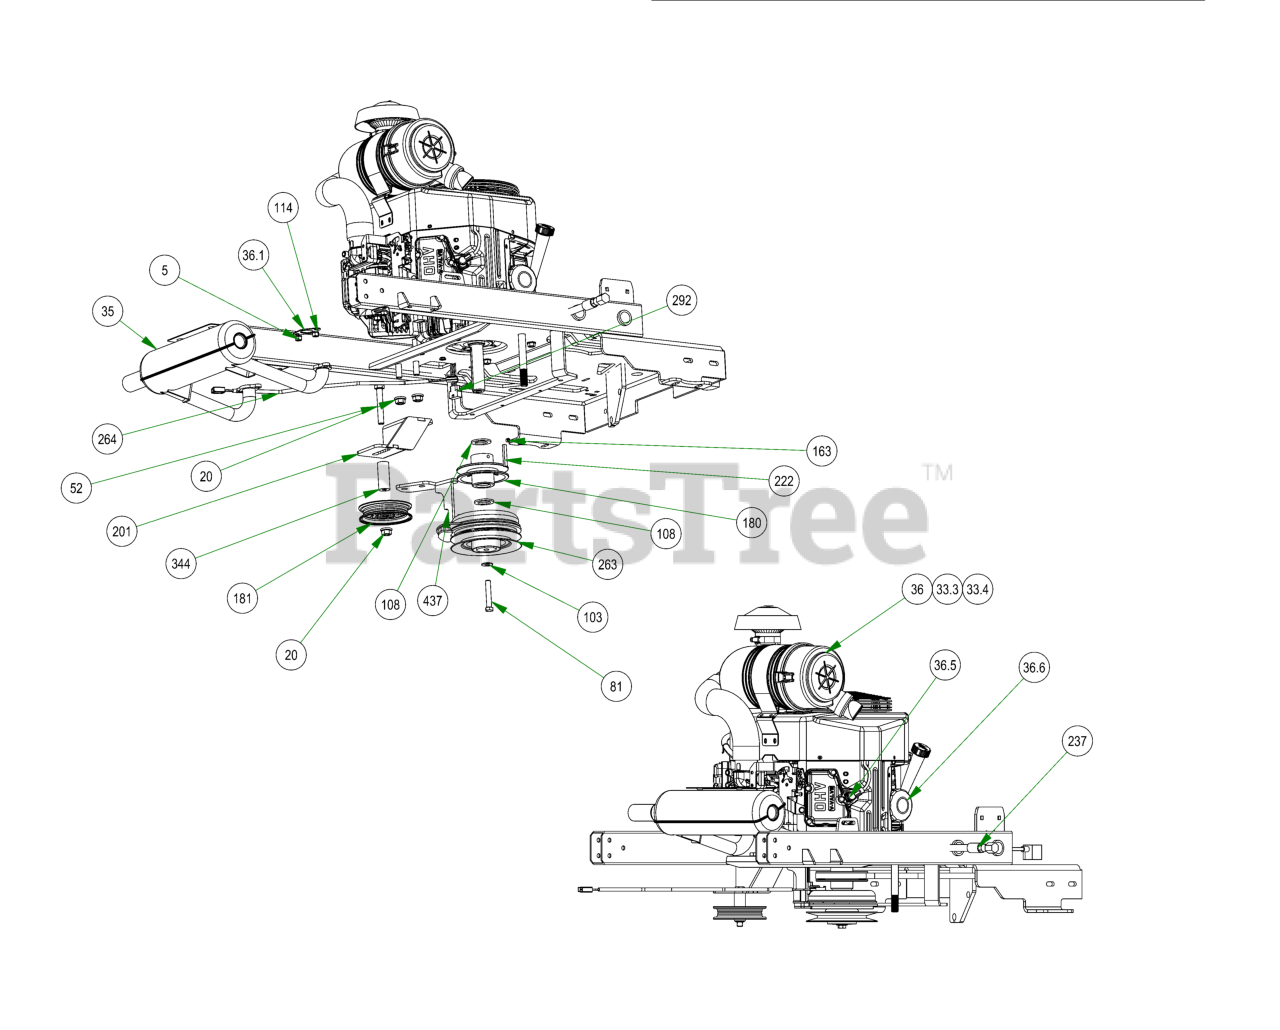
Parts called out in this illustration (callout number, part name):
5	M8-1.25 DIN 934 HEX NUT (CL.8) ZINC
20	1/2-13 NYLON INSERT FLANGE LOCKNUT ZINC
25	5/16-18 NYLON INSERT JAM LOCKNUT ZINC
35	Exhaust-Stand On-FX691V Kawasaki
36	FX-730 Kawasaki
36.1	Exhaust Gasket
36.2	Universal Inline Fuel Filter
36.3	Canister Air Filter- Outer
36.4	Canister Air Filter- Inner
36.5	Spark Plug - Kawasaki
36.6	Oil Filter
39	Exhaust Gasket
52	1/2-13 X 3-1/4 HEX CAP SCREW (GR.5) ZINC
60	3/8-16 X 1-1/8HEX WASHER UNSLOT SERRATED (TRI-LOB) TRS
74	1/2-13 X 1-1/2 HEX CAP SCREW (GR.5) ZINC
81	7/16-20 X 2-1/2 HEX CAP SCREW (GR.8) ZINC YELLOW
83	M8-1.25 X 20MM DIN 933 HEX TAP BOLT (CL 8.8) ZINC
103	3/8 FLAT WASHER USS (1" OD) ZINC
108	1.140 ID X 1.750 OD X .132 THICK FLAT WASHER PLAIN
114	5/16 SPLIT LOCKWASHER ZINC
163	5/16-24 X 1/4 SOCKET SET SCREW (CUP PT) PLAIN
180	4 3/4 Motor Pulley
181	4 3/4 Idler Pulley - ABFI-76
201	Idler Pulley Bracket Weldment 2019 Stand On
219	2019 Stand On Pump Belt (Timken# 47-2827)
222	1/4 X 2 SQ MACHINERY KEY 1018 STL PLAIN
237	Kawasaki Oil Drain
251	24 inch Black Cable – MZ/ZT
263	Clutch Assembly
264	Clutch Pigtail
265	2019 Stand On Frame
292	2019 Harness Adaptor-Gen2 FX-ALL
344	Stand On Spacer 2.5''
437	2019 Stand On Clutch Stop Bracket
